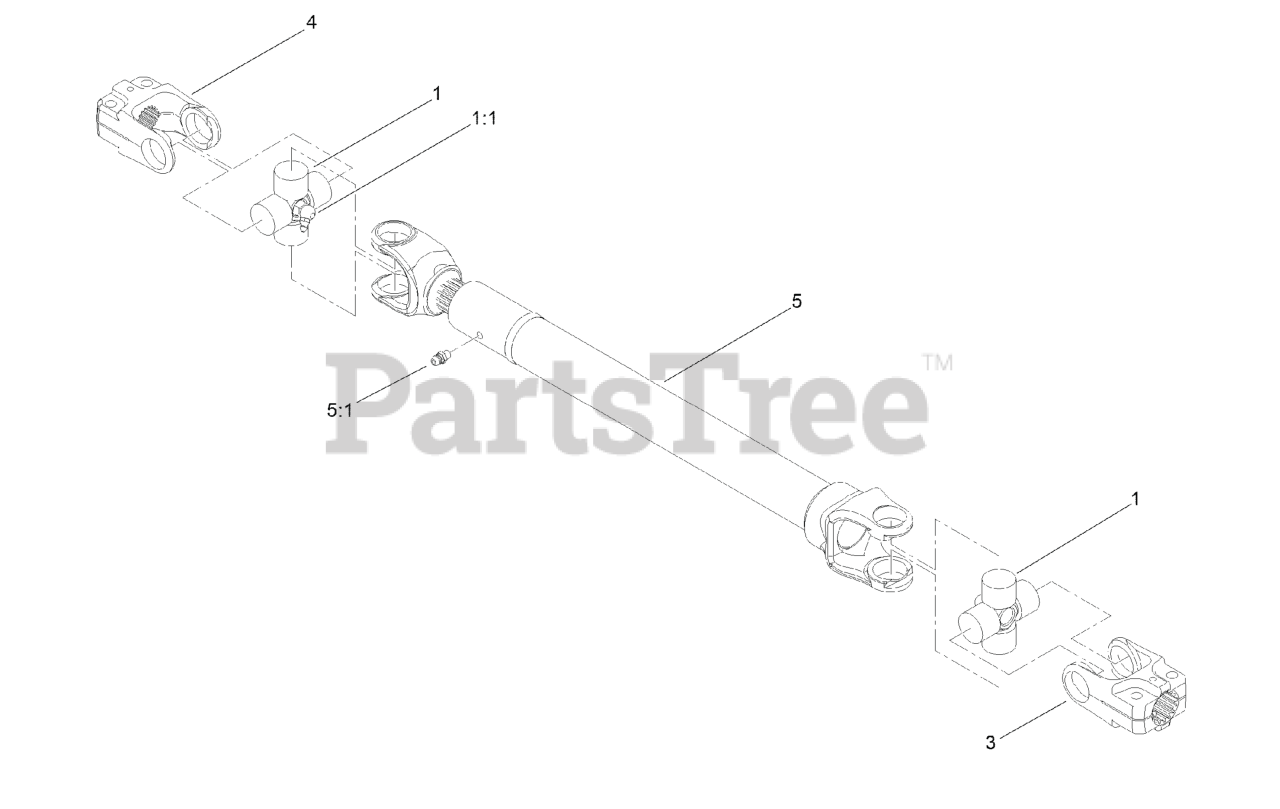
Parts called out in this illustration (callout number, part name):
1	CROSS AND BEARING KIT
1:1	FITTING-GREASE
3	YOKE-END
4	YOKE-END
5	Tube-Yoke, Slip
5:1	FITTING-GREASE
